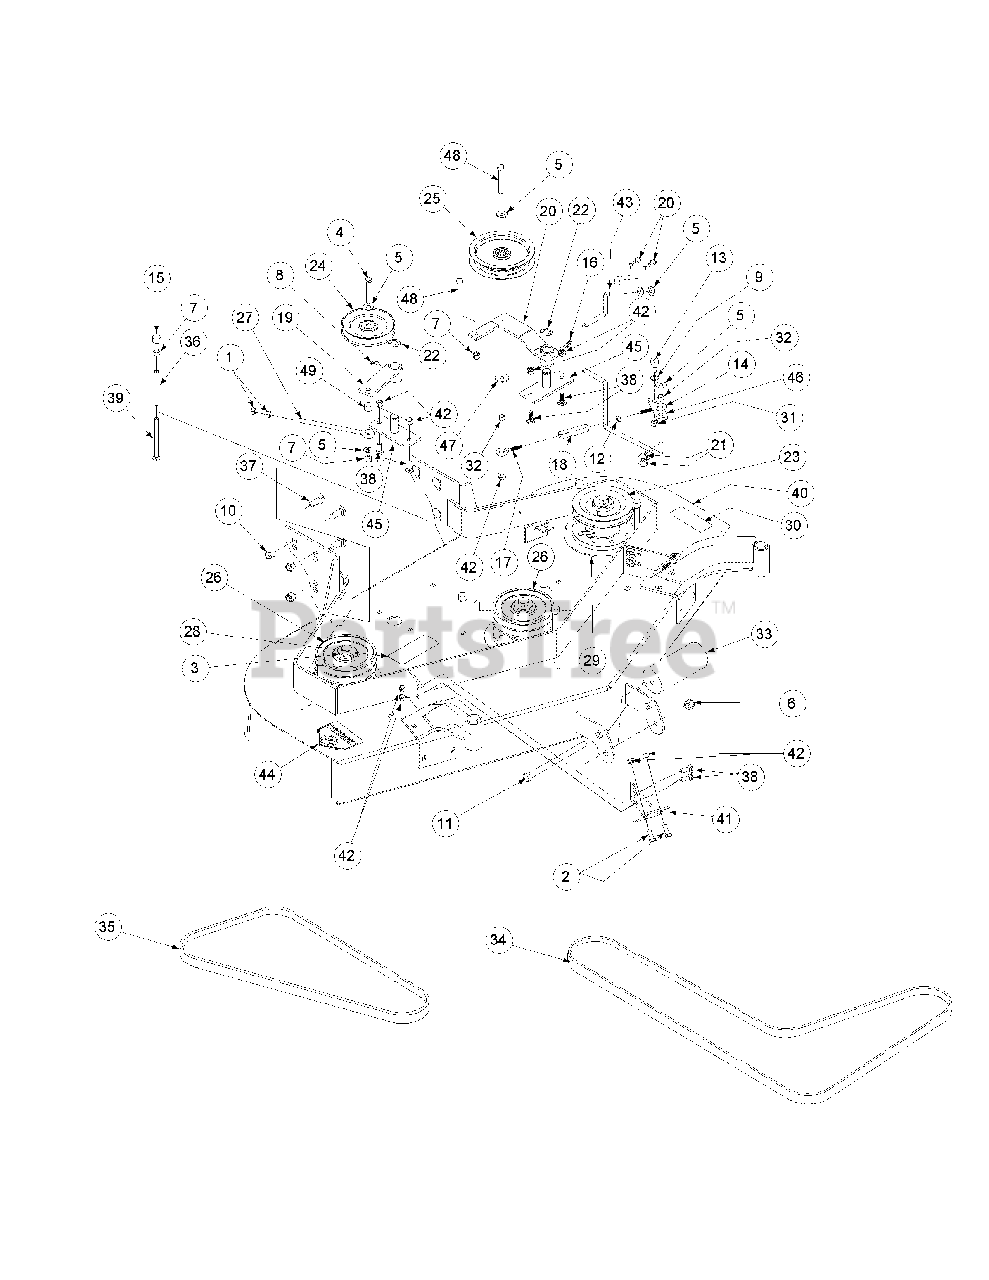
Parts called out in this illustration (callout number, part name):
1	Hex Nut, 3/8-16
2	Hex Cap Screw, 3/8-16, 1
3	Flat Washer, 5/8
4	Hex Cap Screw, 3/8-16, 2-1/4
5	Flat Washer, 3/8 Zinc
6	Nut, 1/2-20, Lock
7	Lock Nut, Nylon Insert, 3/8-16
8	Grease Fitting, 1/4-28, 90°
9	Shim Washer
10	Nut, Flange Lock, 1/2-13
11	Hex Cap Screw, 1/2-20, 7.50
12	Hex Nut, 5/16-18
13	Shoulder Bolt
14	Eye Bolt, Right Hand
15	Vinyl Cap
16	Grease Fitting, 1/4-28, 45°
17	Eye Bolt, Left Hand
18	Turnbuckle
19	Idler Arm "B"
20	Idler Arm "A"
21	Hair Pin, 3/8-1/2
23	Deck Pulley
24	Idler Pulley
25	Idler Deck Take-up
26	Double Pulley
27	Rod Belt Tensioner
28	Decal Rotating Blade
29	Spindle Backing Plate
30	Decal Warning Shield Missing
31	Lock Nut, Metal, 3/8-16
32	Sleve Turnbuckle
33	Front Roller
34	Drive Belt
35	Drive Belt
36	Spacer Belt Guide
37	Carriage Bolt, 1/2-13 x 1-1/4
38	Carriage Bolt, 3/8-16 x 1-1/4
39	Carriage Bolt, 3/8-16 x 4-1/2
40	Mower Deck Weldment, 52"
41	Caster Support Assembly
42	Nut, Hex Flange Lock, 3/8-16
43	Rod Clutch Link
44	Decal, Danger Hands and Feet
45	Idler Base
47	Washer, 1.25 x .411 x .100
48	Hex Cap Screw, 3/8-16, 2.75
49	Sleeve Tensioner
